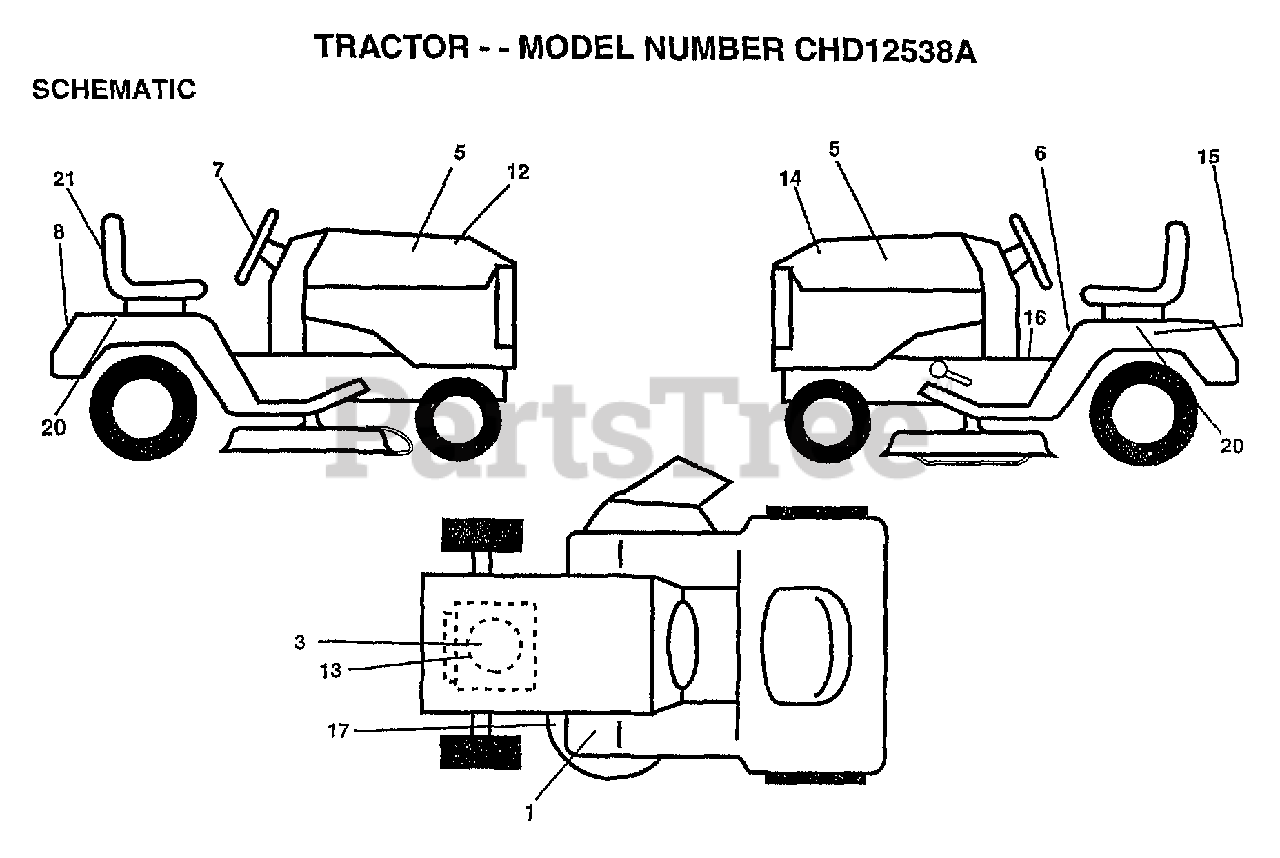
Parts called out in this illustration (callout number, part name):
1	DECAL T
2	DECAL, HP ENGINE
5	"DECAL PENL,SIDE"
6	DECAL.CAUT.ENG/FR
7	"DECAL INS,STRG WH"
8	DECAL-FENDER
11	"DECAL MOWER,HOME"
12	"DECAL HOOD,RH"
13	"DECAL ENGINE,REPL"
14	DECAL HOOD LH
15	DECAL.BATRY.3-3908
16	"DECAL.OPER,SDL"
17	DECAL
20	"DECAL FENDER,5 SP"
21	"DECAL SEAT,REPLCM"
